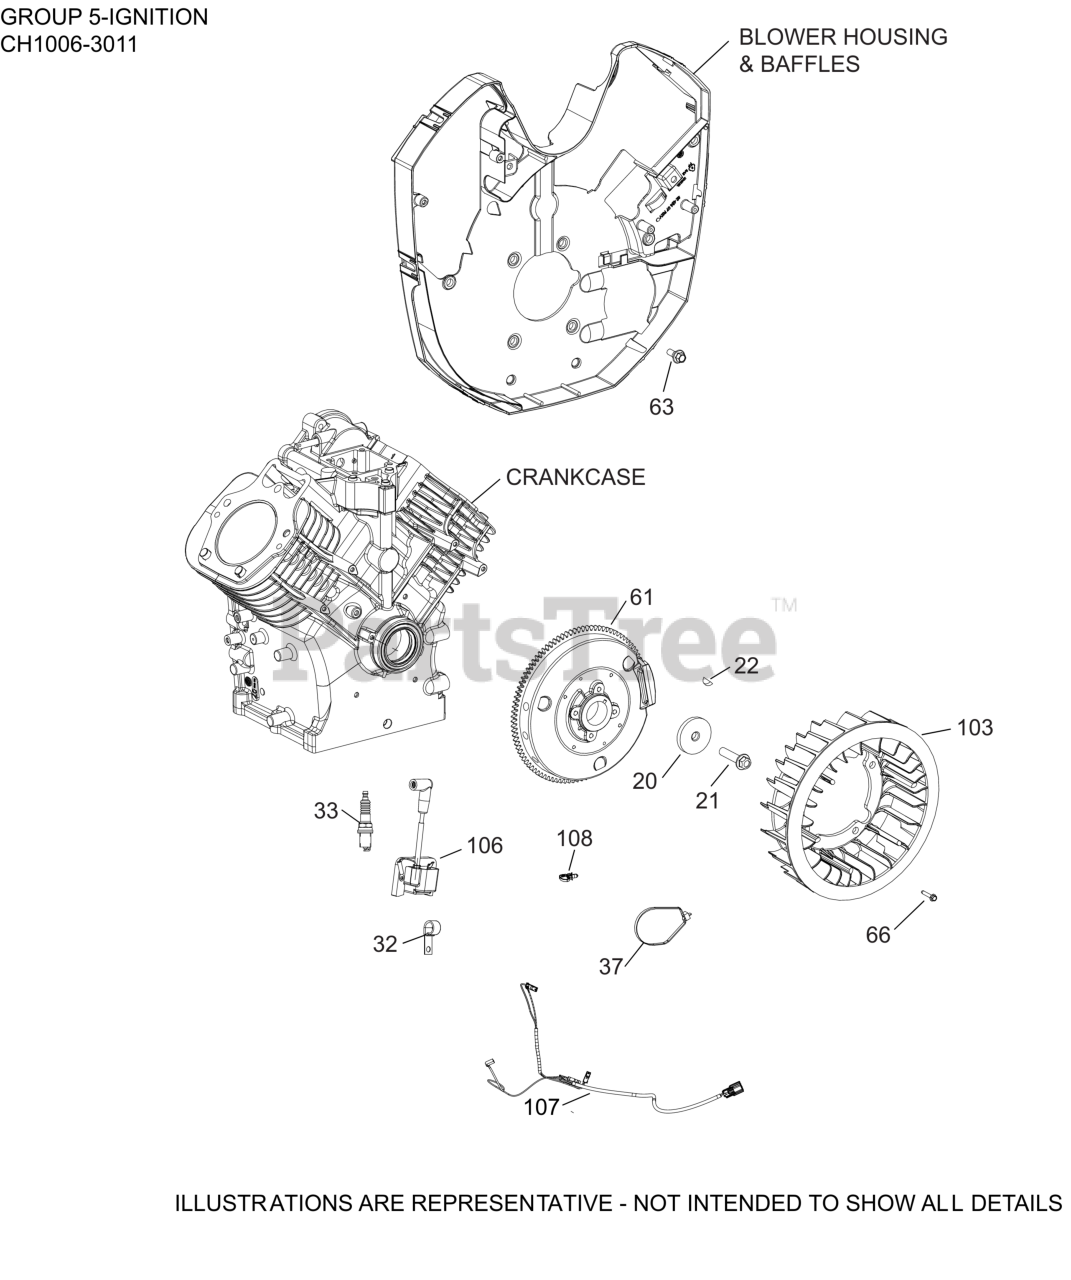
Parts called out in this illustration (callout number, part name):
20	WASHER, FLAT 13/32"
21	SCREW, HEX FLANGE
22	KEY, 3/16" X 5/8"
32	CLIP, CABLE
33	PLUG, SPARK CHAMPION (SERVICE) (XC10YC)
37	TIE, CABLE
61	FLYWHEEL, ASSEMBLY CARB
63	BOLT, SHOULDER
66	SCREW, THREAD THROWING
106	MODULE, DIGITAL IGNITION (LP/NG)
107	HARNESS, WIRING ASSEMBLY (DUAL TIMING)
108	TIE, WIRE
